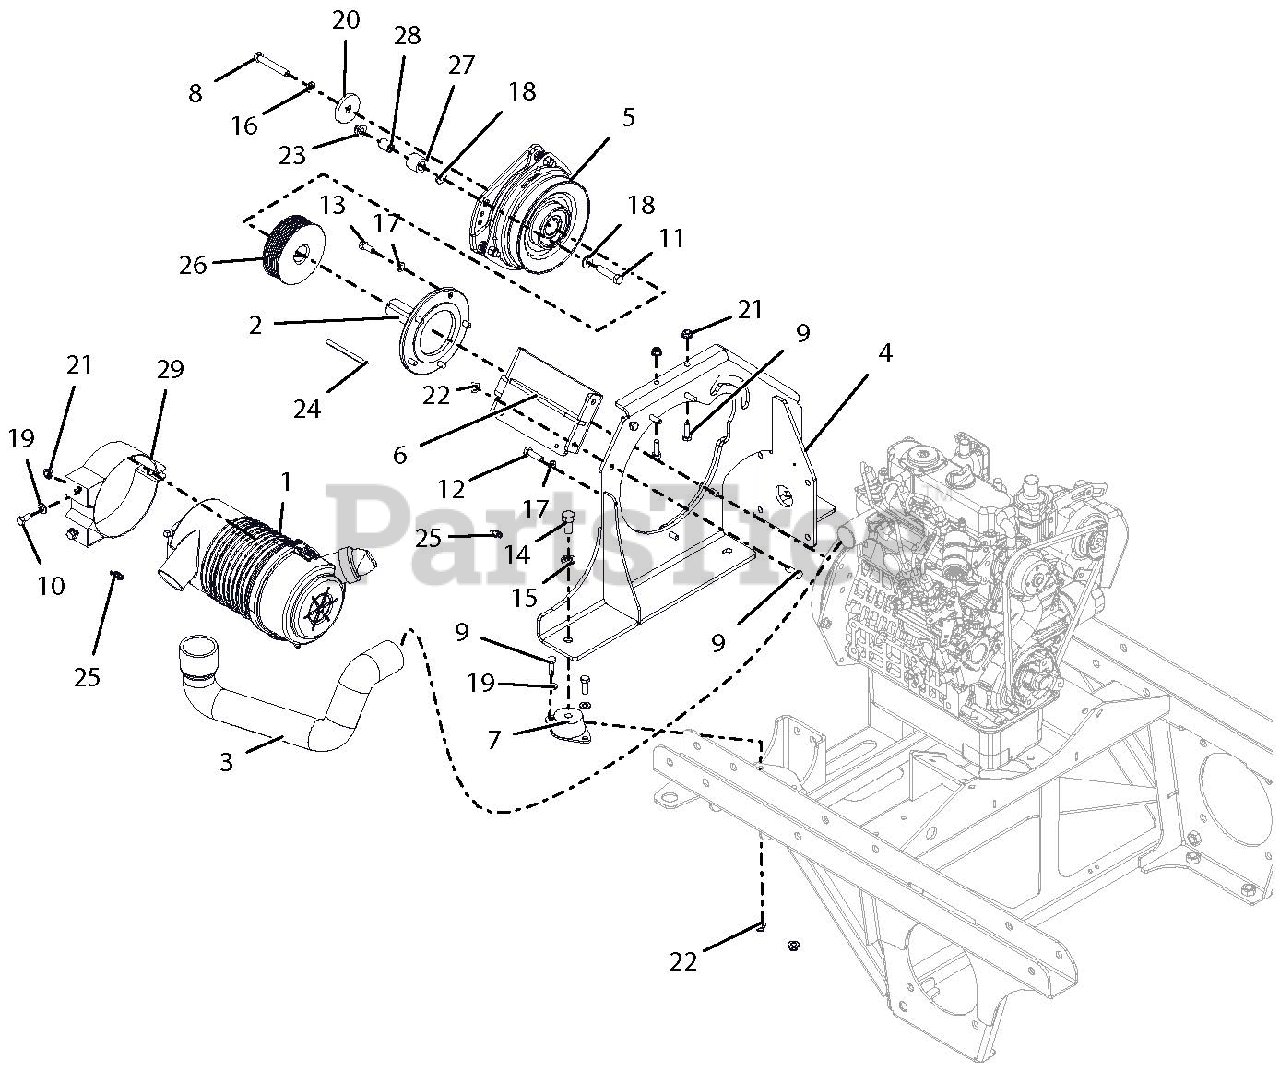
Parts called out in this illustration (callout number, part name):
1	AIR, CLEANER
2	SHAFT, STUB KUBOTA DIESEL MACHINED
3	HOSE, FORMED AIR CLEANER OUTLET
4	WLDMT, ENGINE /GEARBOX MNT
5	CLUTCH, DIESEL REVERSE MOUNT
6	WLDMT, CLUTCH STOP
7	MOUNT, ENGINE. VIBRATION ISO
8	BOLT, HEX 3/8-24 x 2.50 GR5 YZ EP80
9	BLT-HEX .31-18X1.00 GR5 YWZC
10	BLT-HEX .31-18X.75 GR5 YWZC
11	BLT-HEX .38-16X1.75 GR5 YWZC
12	@BLT-HEX M8 X 1.25X30 GR5 YWZC
13	@BLT-HEX M8-1.25X20 YWZC
14	BLT-HEX .50-20X1.00 GR5 YWZC
15	WSHR-LK .50X.125 REG YWZC
16	WSHR-LK .38X.094 REG YWZC
17	WSHR, LOCK M8 YWZC
18	WSHR-FL-STL.38X.875X.083 YWZC
19	WSHR-FL-STL.344X.688X.065YWZC
20	WSHR-FL-STL .469X2.00X.25 YWZC
21	@NUT-SPNLK-FLG .312-18 YWZC
22	NUT-LK-NYL-FLG .31-18 YWZC
23	NUT-LK-NYL-FLG .38-16 YWZC
24	KEY-SQ .250X.250X3.50
25	CLAMP, HOSE #32 1.56"-2.50"
26	SHEAVE, POLY -V 4.125 X 4.650
27	BUMPER, RUBBER .62 X 1.0 X .88 LG
28	BUSHING, SLV .407X.625X.813
29	BRKT, AIR CLEANER MOUNT
